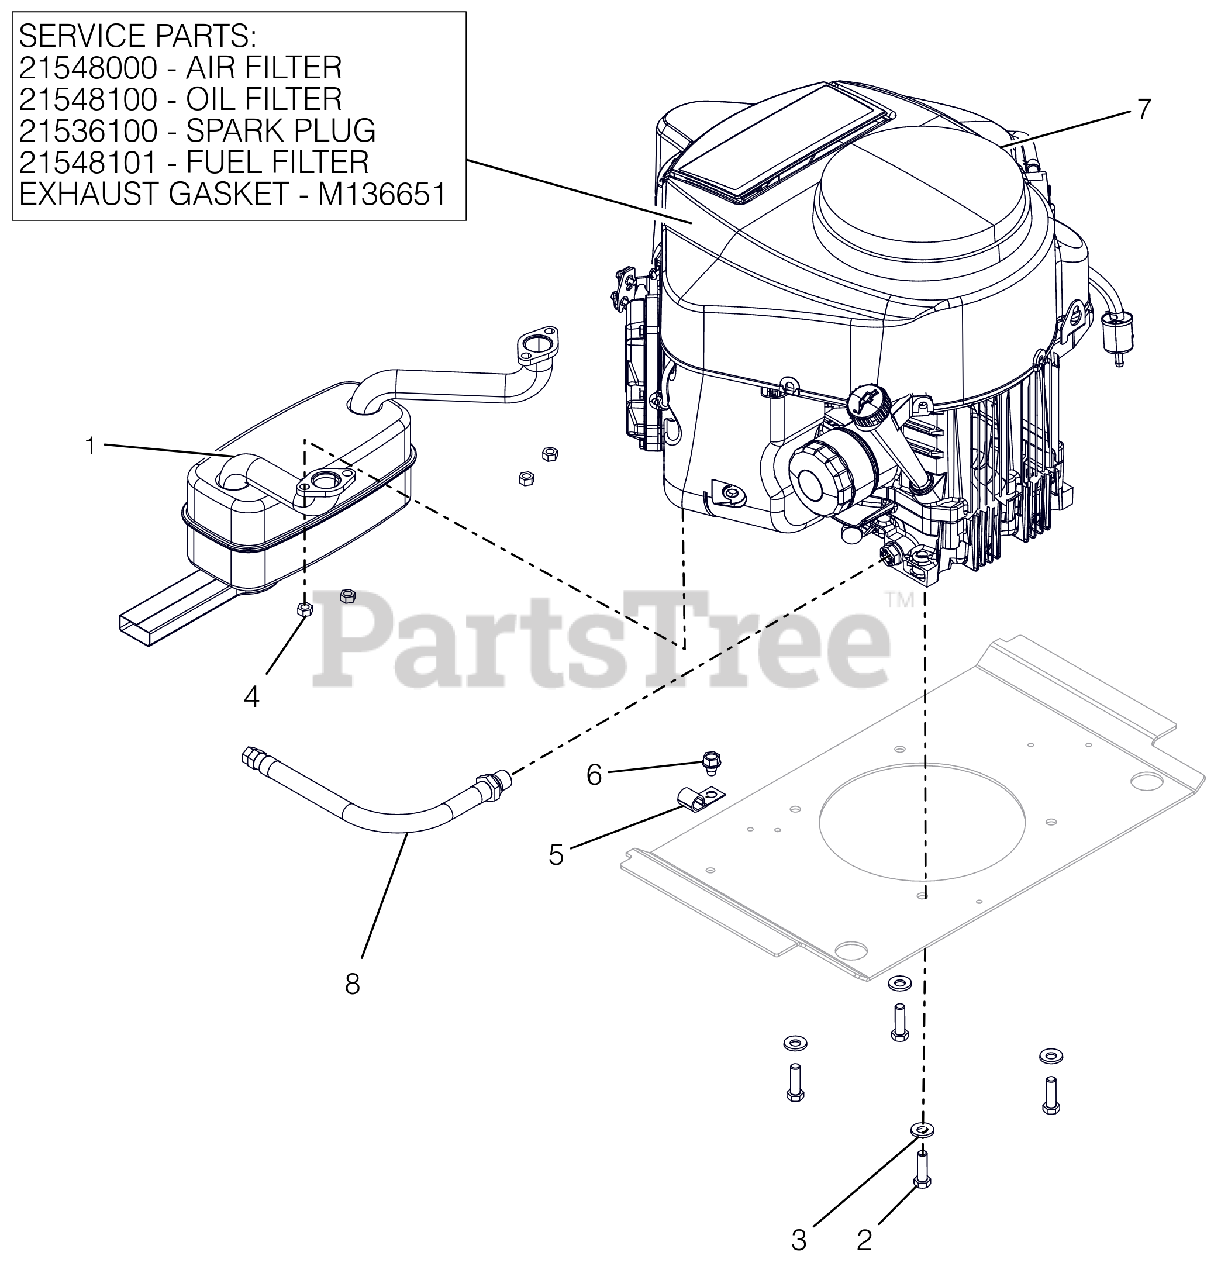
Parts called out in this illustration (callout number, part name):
1	MUFFLER, KAWASAKI
2	BLT-HEX.38-16X1.25 G5YZ NYTORQ
3	WASHER, 3/8" SPRING DISC
4	NUT-LK-TOP M8-1.25 YWZC
5	J-CLAMP
6	@SCR-TAP .38-16X.50 HWH TR YWZ
7	ENGINE, KAWASAKI FR730 24HP
7	AIR FILTER, KAWASAKI FR
7	OIL FILTER, KAWASAKI FR
7	PLUG, SPARK
7	FUEL FILTER-KAWASAKI FR
7	GASKET, MUFFLER #
8	HOSE, OIL DRAIN
